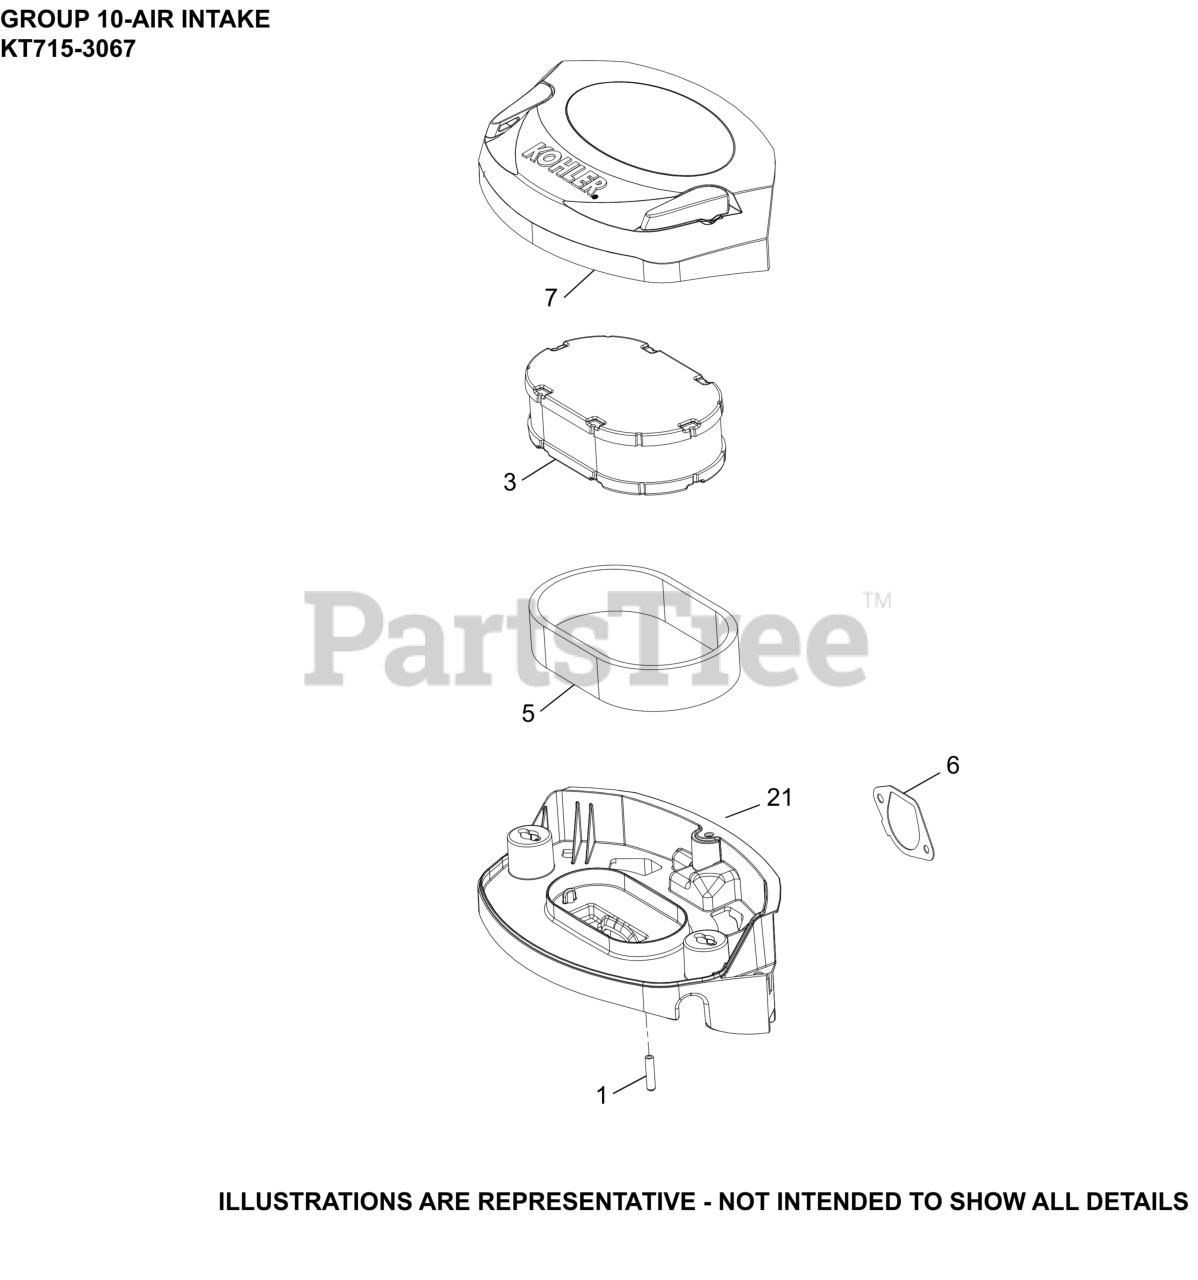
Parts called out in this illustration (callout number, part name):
1	CAP, MASKING
3	ELEMENT, AIR FILTER
5	ELEMENT, PRE-CLEANER
6	GASKET, AIR CLEANER BASE
7	COVER ASSEMBLY, AIR CLEANER
21	BASE ASSEMBLY, AIR CLEANER
